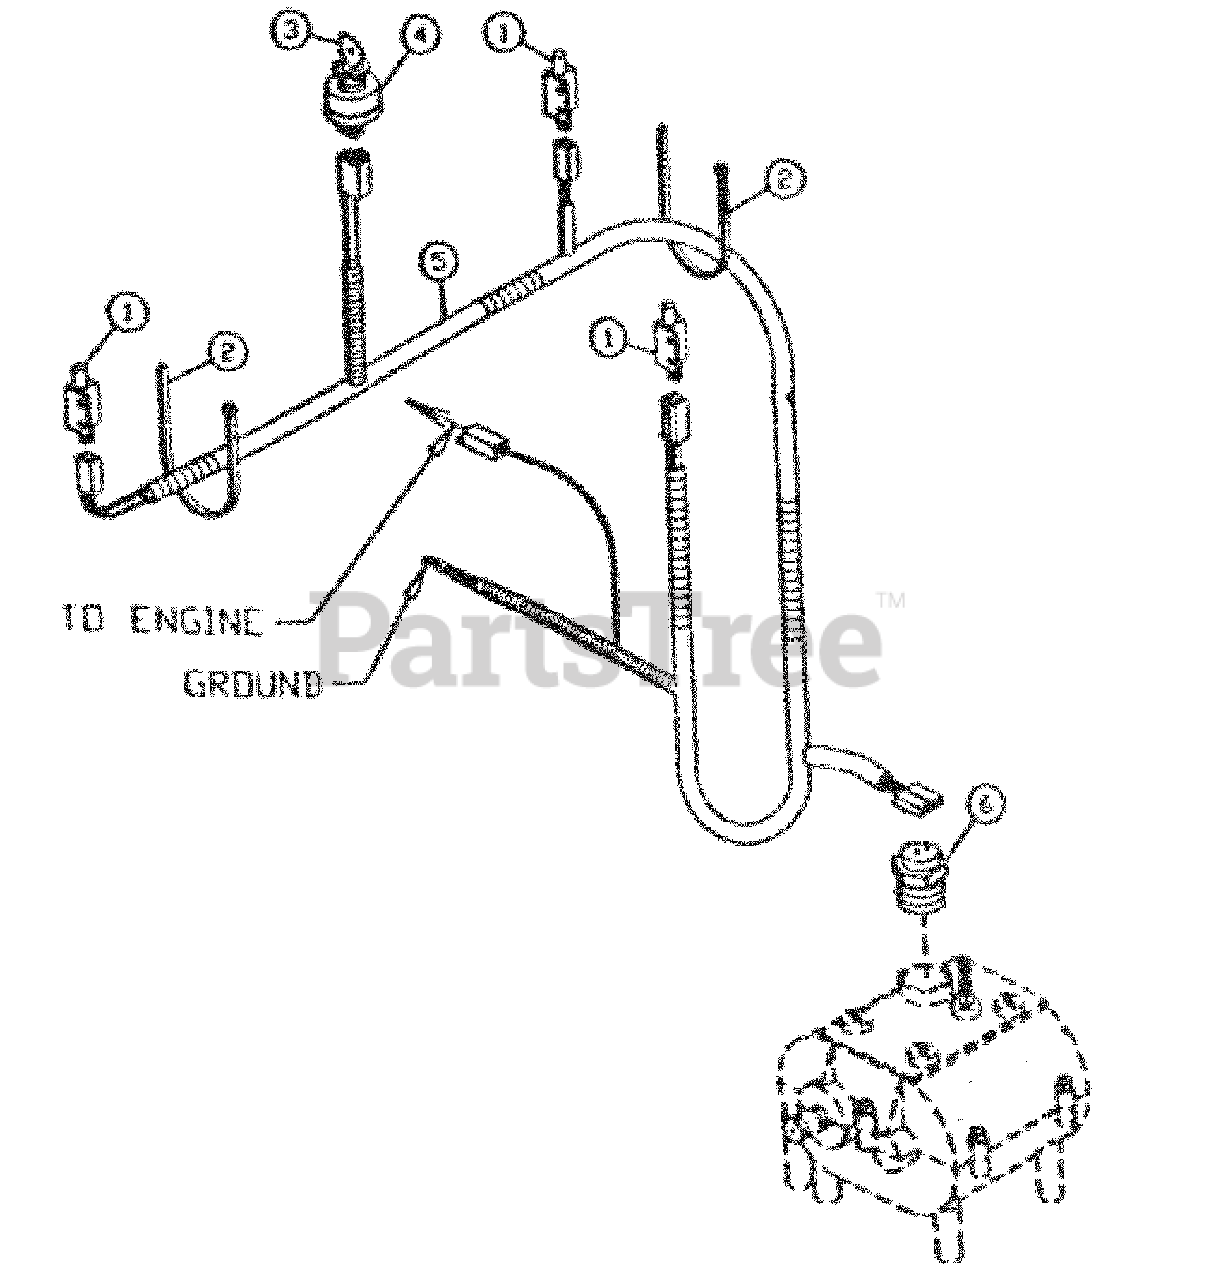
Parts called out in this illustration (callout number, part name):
1	100-060 SWITCH
3	100-114 KEY SWITCH & KEY
4	100-114 KEY SWITCH & KEY
5	100-115 WIRING HARNESS
6	100-055 NEUTRAL SWITCH
